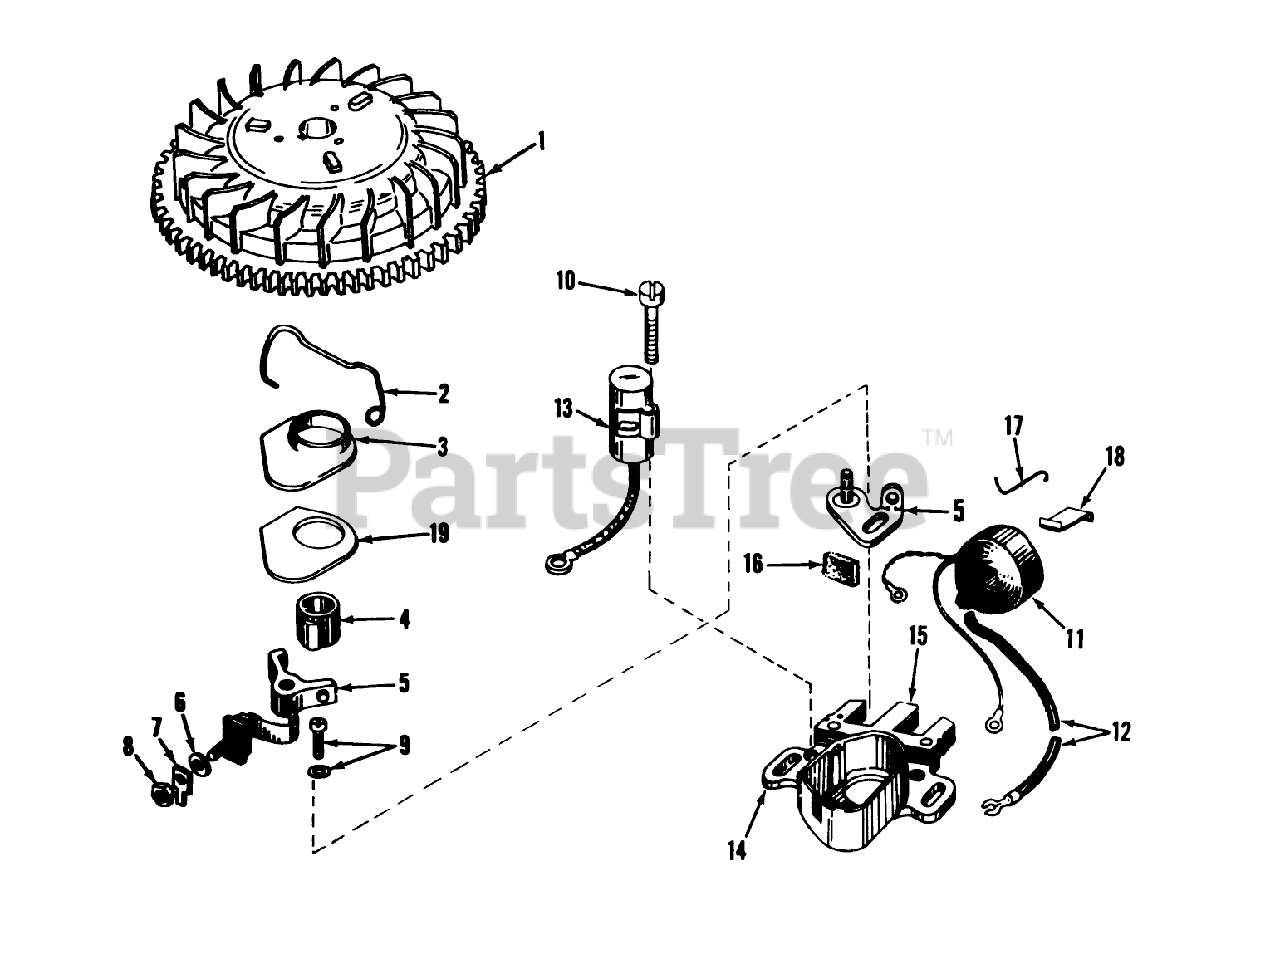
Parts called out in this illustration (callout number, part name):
1	FIywheel
2	Spring Breaker Box
3	Cover, Dust
4	Cam, Breaker
5	Breaker Assy.
6	Washer
7	Terminal, Ground
8	DECAL
9	Breaker Screw
10	Condenser Screw
11	Coil Assy. (Incl. No. 12)
12	Wire, Lead
13	Condenser
14	Core Plate
15	Stator Assy., (Incl. Nos. 2, 3, 5 thru 14 16 thru 19)
16	Felt,Cam Wiper
17	Clip, Coil
18	Spring Coil Wedge
19	Gasket Dust Cover
